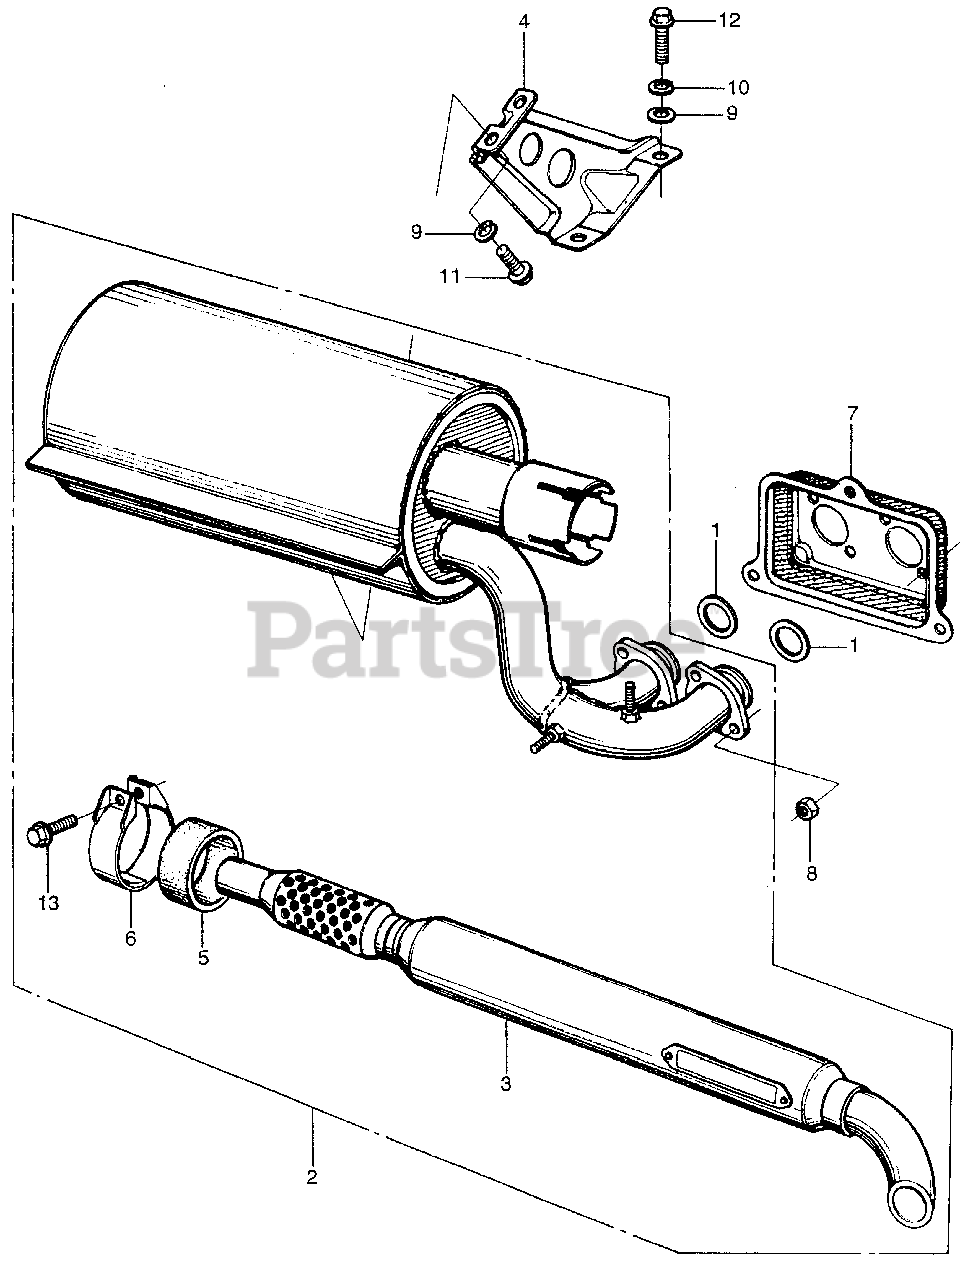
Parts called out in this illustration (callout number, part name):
1	GASKET, EX. PIPE
2	MUFFLER, EX.
3	PIPE, TAIL
4	STAY, MUFFLER
5	GASKET, MUFFLER
7	SEAL, EX. PIPE (NOT AVAILABLE)
8	NUT, HEX. (8MM)
9	WASHER, PLAIN (8MM)
10	WASHER, SPRING (8MM)
11	BOLT, FLANGE (8X16)
12	BOLT, FLANGE (8X20)
13	BOLT, FLANGE (8X25)
